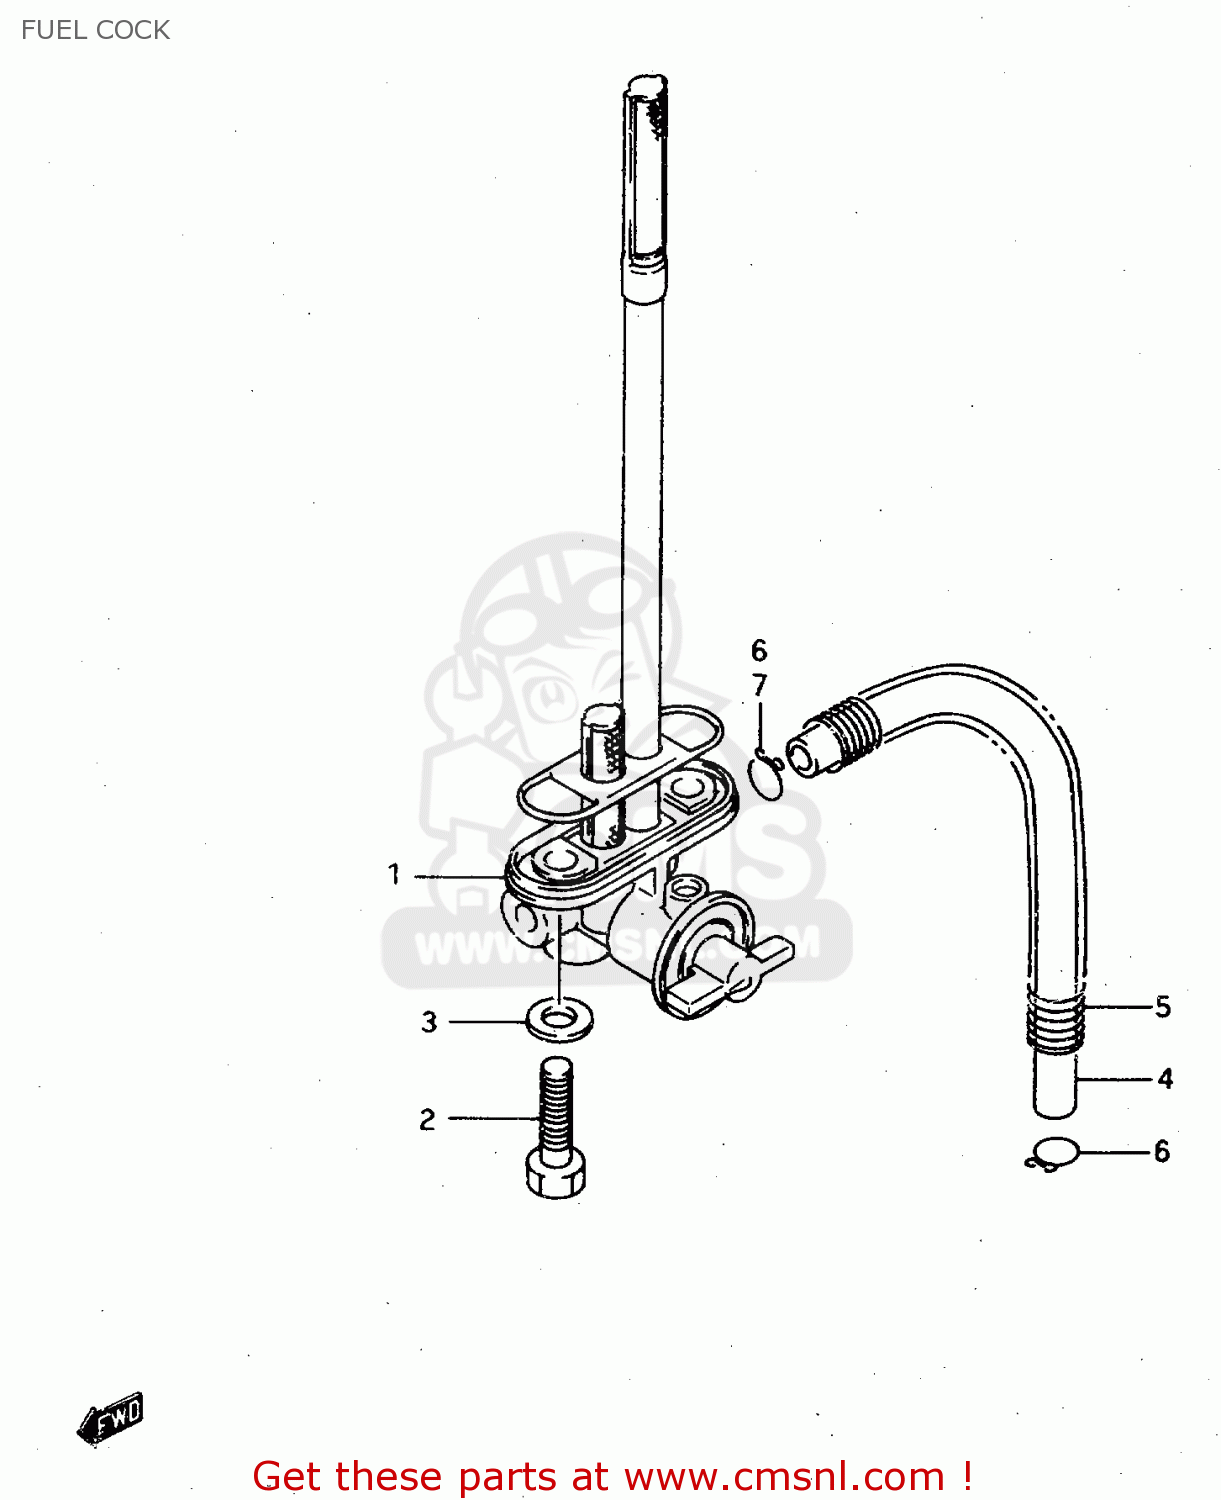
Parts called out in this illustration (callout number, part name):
1	COCK ASSY,FUEL
2	BOLT(6X20)
3	GASKET(6.4X11.5X0.8) (NAS)
4	HOSE
5	SPRING
6	CLIP
7	CLIP
